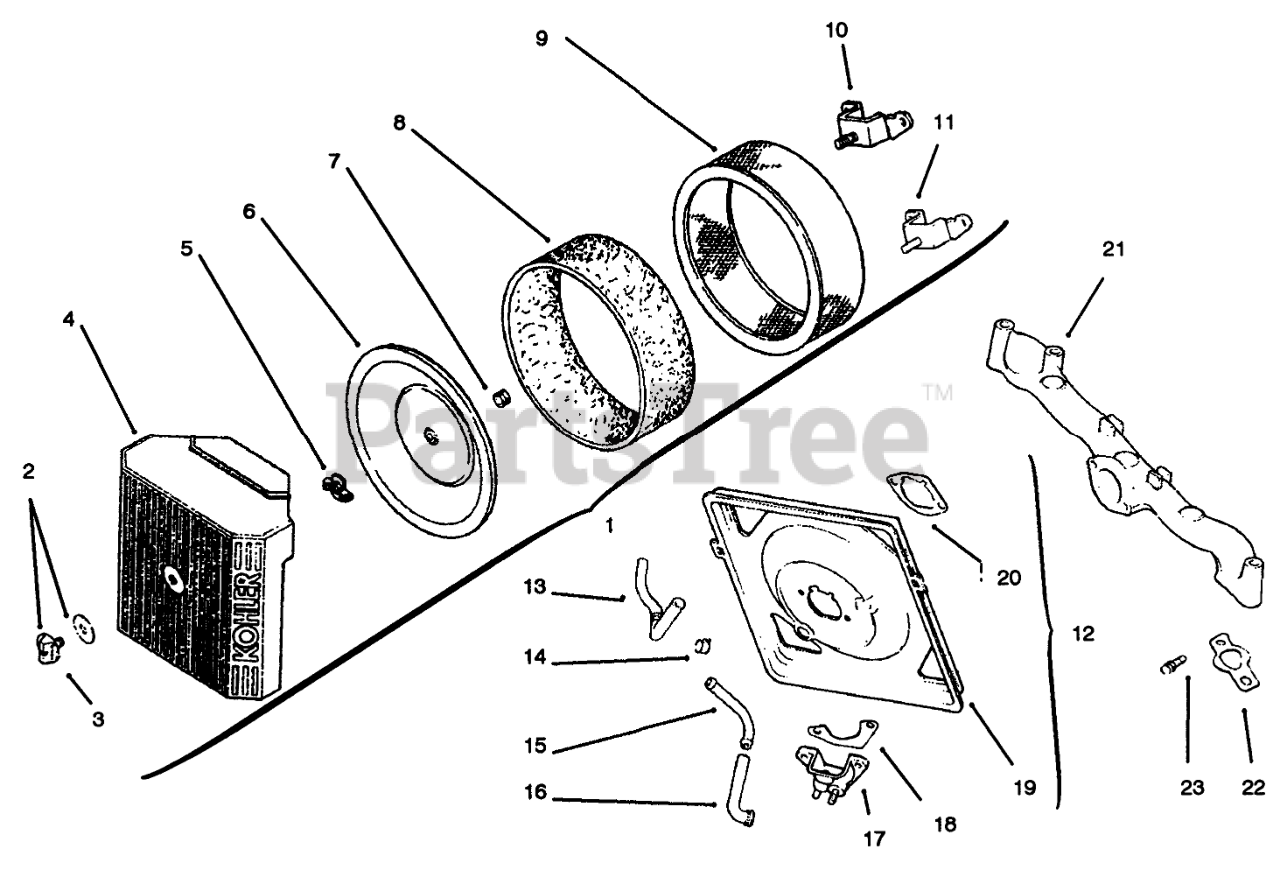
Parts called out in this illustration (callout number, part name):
1	Kit-Air Cleaner Cover
2	Kit-Knob W/Gasket
3	Knob-Cover
4	Cover-Air Cleaner
5	Nut-Wing
6	Cover-Inner Air Cleaner
7	Seal-Air Intake
8	Element-Precleaner
9	Element-Air Cleaner
10	Bracket-Air Cleaner Base
11	Bracket-Air Cleaner
12	Kit-Air Cleaner Base
13	Hose-Breather
14	Clamp
15	Fitting
16	Hose-Breather
17	Cup-Fuel Spitback
18	Gasket-Fuel Spitback Cup
19	Base-Air Cleaner
20	Gasket-A/C Base
21	Manifold-Intake
22	Gasket-Intake Manifold
